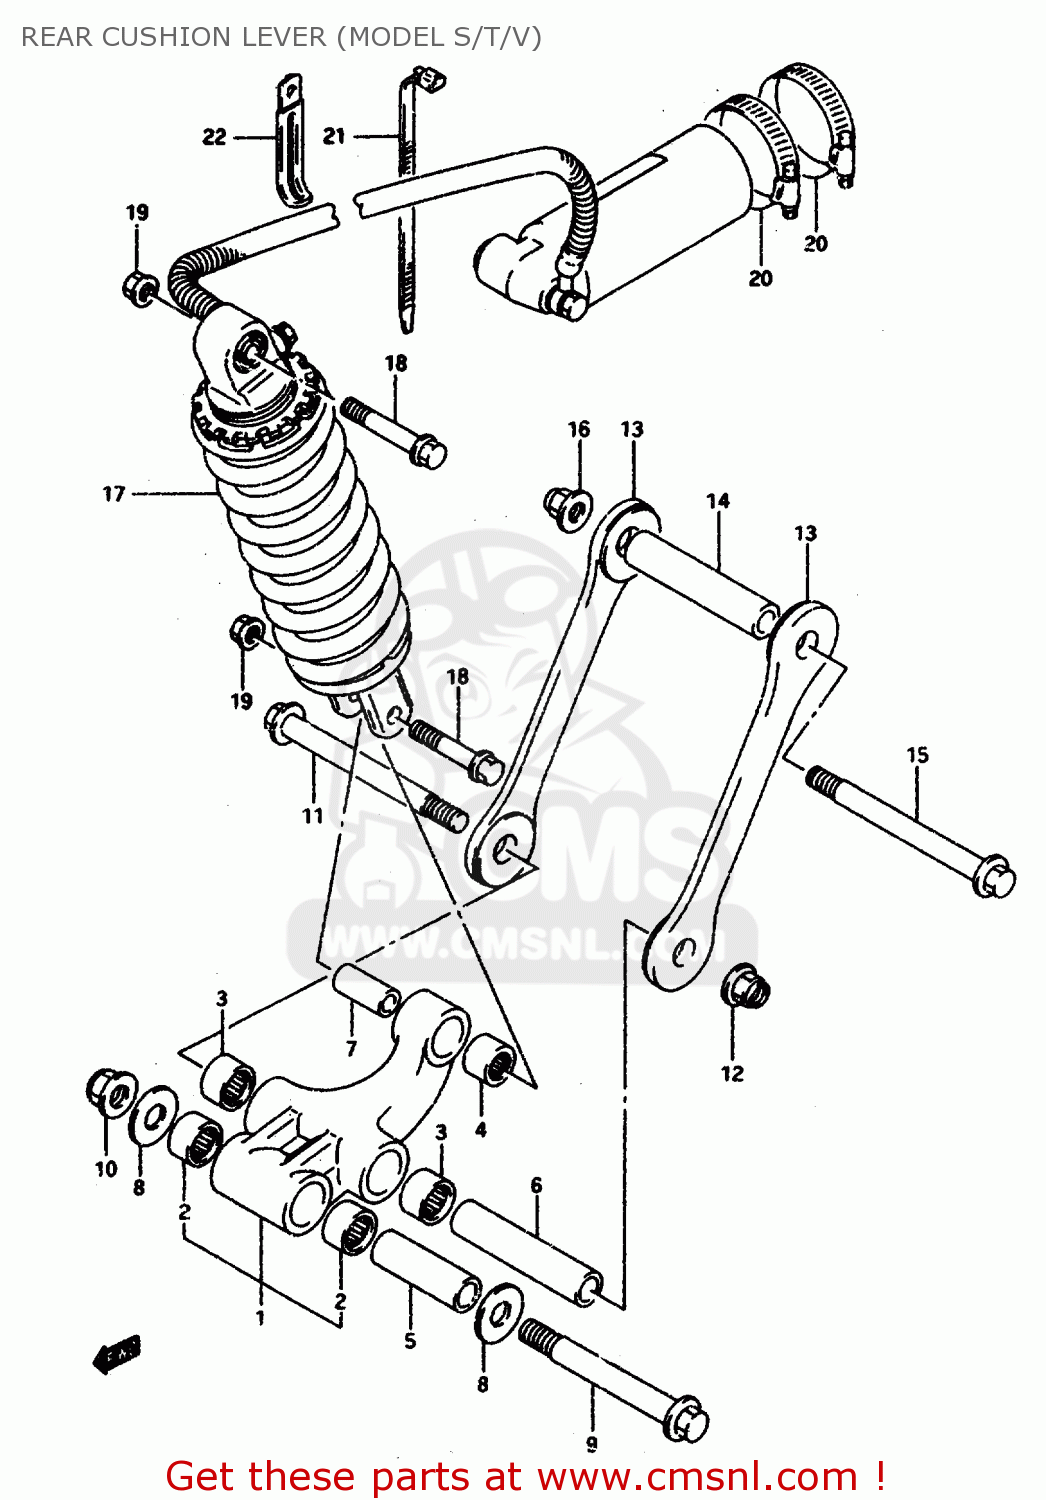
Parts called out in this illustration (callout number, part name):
1	LEVER SET,REAR CUSHION
2	BEARING(20X27X23.5)
3	BEARING(17X24X20)
4	BEARING(17X24X26)
5	SPACER,RR CUSHION LEVER
6	SPACER(12X17X85)
7	SPACER,RR CUSHION LEVER
8	WASHER
9	SHAFT,RR CUSHION LEVER FR
10	NUT
11	BOLT(12X115)
12	NUT 12MM
13	ROD COMP,REAR CUSHION
14	SPACER(12X17X85)
15	BOLT(12X115)
16	NUT 12MM
17	ABSORBER ASSY,RR SHOCK
18	BOLT(10X58)
19	NUT
20	CLAMP
21	CLAMP L:165
22	CLAMP
23	CLAMP(L:165)
24	CLAMP
